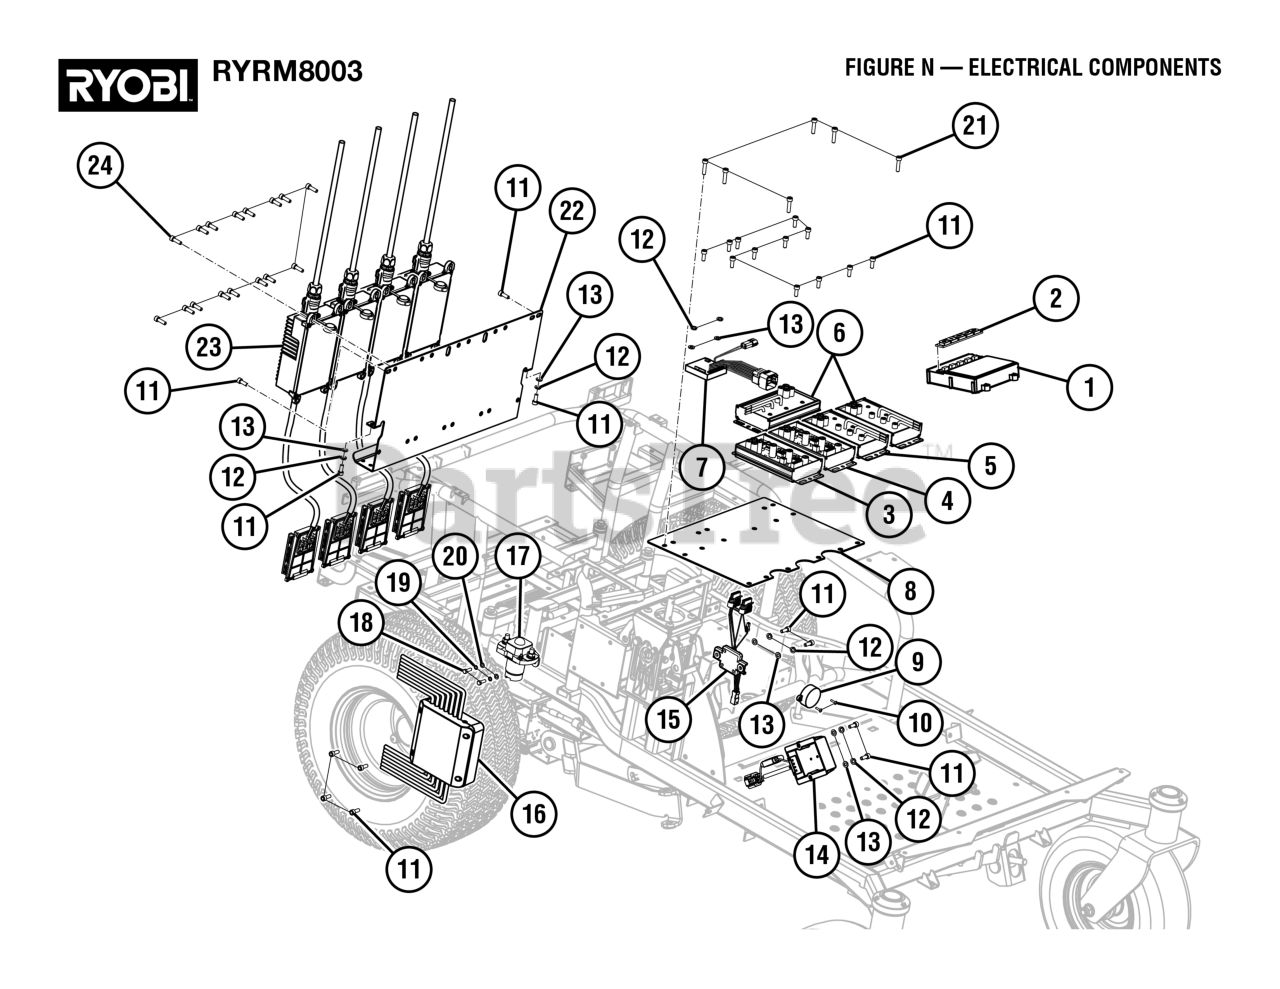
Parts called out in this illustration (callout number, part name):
1	LCD Module Assembly
2	LCD Buttons
3	Drive Deck Controller (Right)
4	Drive Deck Controller (Left)
5	Deck Controller (Primary)
6	Deck Controller (Secondary)
7	TIC Assembly
8	Controller Mounting Plate
9	Beeper, ZTR
10	Screw (M3 x 12 mm, Pan Hd.)
11	Screw (M6 x 16 mm, Soc. Hd.)
12	Spring Washer (M6) (For Deck Motor Controllers T & U)
13	Washer (OD12 x ID6.4 x 1.6t) (For Deck Motor Controllers T & U)
14	DC to DC Converter, ZTR
15	Mixing Board Assembly
16	Terminal Box Assembly
17	Main Relay (G)
18	Bolt (M5 x 16 mm, Hex hd.) (For Main Relay G)
19	Lock Washer (For Main Relay G)
20	Washer (OD12 x ID5.3 x 1t) (For Main Relay G and Power Converter I)
21	Bolt (M6 x 25 mm, Socket Hd.)
22	Booster Mounting Plate
23	80V Booster
24	Screw (M6 x 20 mm, Soc. Hd.)
